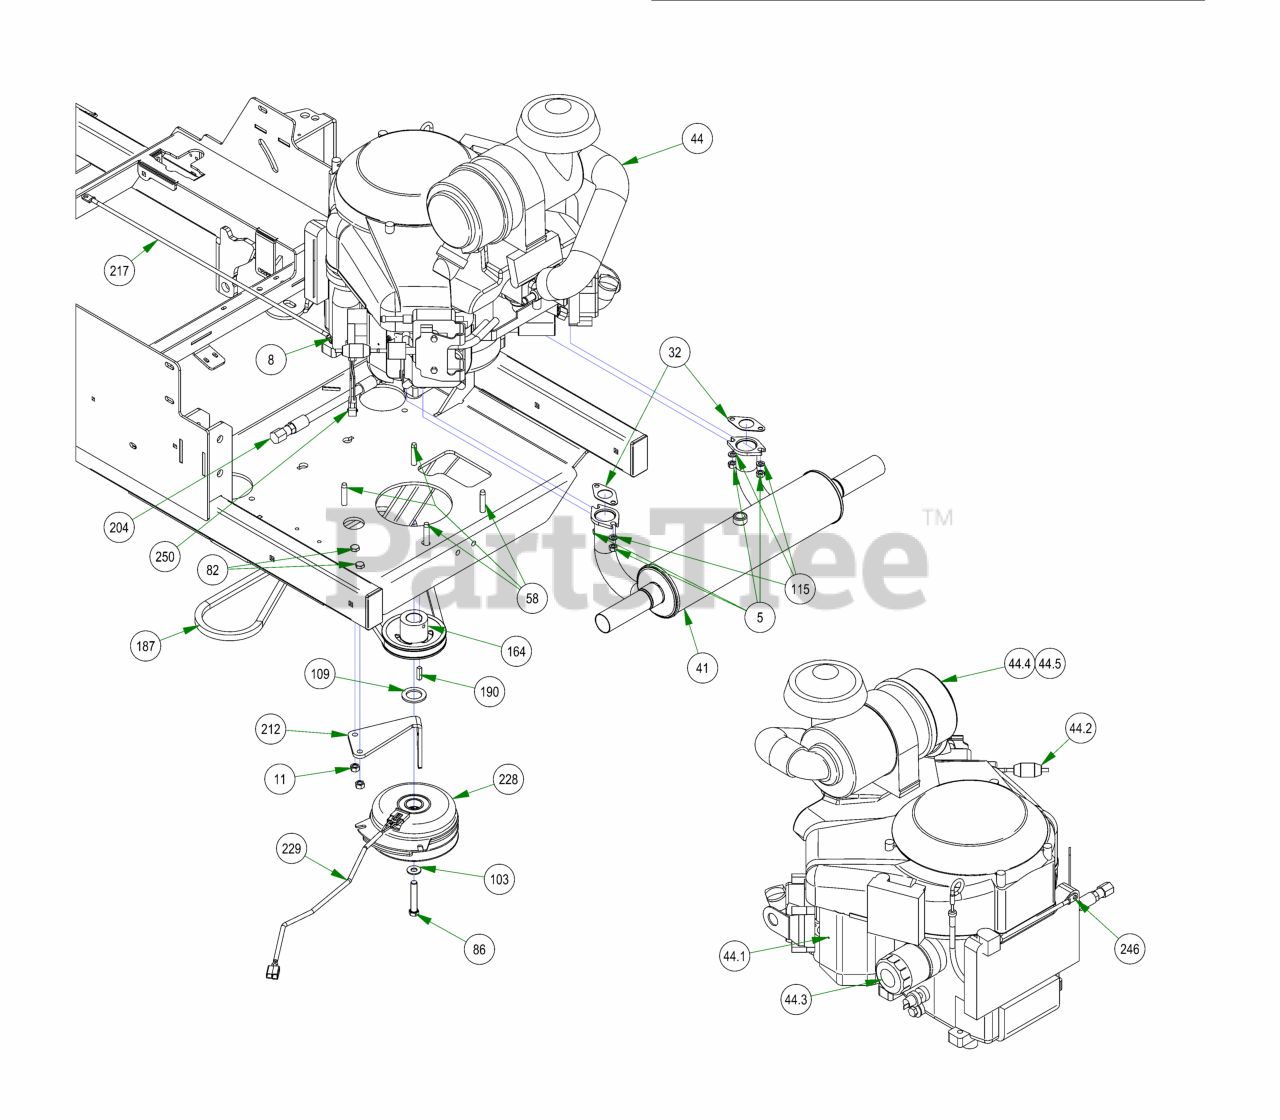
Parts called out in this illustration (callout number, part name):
5	M8-1.25 DIN 934 HEX NUT (CL.8) ZINC
8	3/8-16 HEX SERRATED FLANGE NUT HARD/ZINC
11	3/8-16 HEX NUT ZINC
31	1 1/2 x 3 Frame Plug
32	Exhaust Gasket for 23 Vanguard
41	Muffler for 36Hp Vanguard
44	993cc Vanguard Engine
44.1	Spark Plug
44.2	Universal Inline Fuel Filter
44.3	Oil Filter
44.4	Canister Air Filter- Outer
44.5	Canister Air Filter- Inner
58	3/8-16 x 2 Hex/ Trilobe Horizontal Engine Bolt
82	3/8-16 X 1-1/4 HEX CAP SCREW (GR.5) ZINC
86	7/16-20 X 2-1/2 HEX Bolt GR 8 W/ Patch
103	3/8 FLAT WASHER USS (1" OD) ZINC
109	1.140 ID X 1.750 OD X .132 THICK FLAT WASHER PLAIN
115	5/16 SPLIT LOCKWASHER ZINC
164	4 3/4 Motor Pulley
187	2019 Rogue Pump Belt 68"
190	1/4 X 1 SQ MACHINERY KEY 1018 STL PLN
204	14 mm Oil drain Hose 993cc Vanguard
212	PTO Engager Holder
217	24" Red Battery Cable
228	Clutch Assembly
229	Clutch Pigtail
230	2021 Rogue Suspension Frame Painted
246	Starter Cable
250	2019 Harness Adaptor - Vanguard 37 EFI Vert/Horiz
